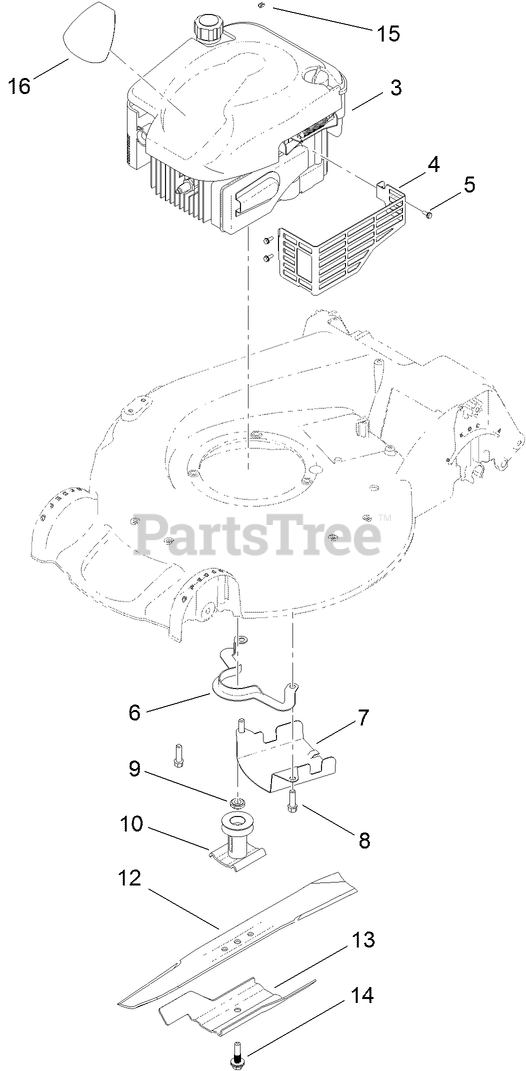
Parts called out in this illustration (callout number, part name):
4	SHIELD-MUFFLER
5	SCREW-TAPTITE
6	GUIDE-BELT
7	SHIELD-GRASS
8	SCREW-TAPTITE
9	SPACER-DRIVER
10	DRIVER-BLADE
13	ACCELERATOR-BLADE
14	BOLT-BLADE
15	STOP-ROPE
16	DECAL-SHROUD
